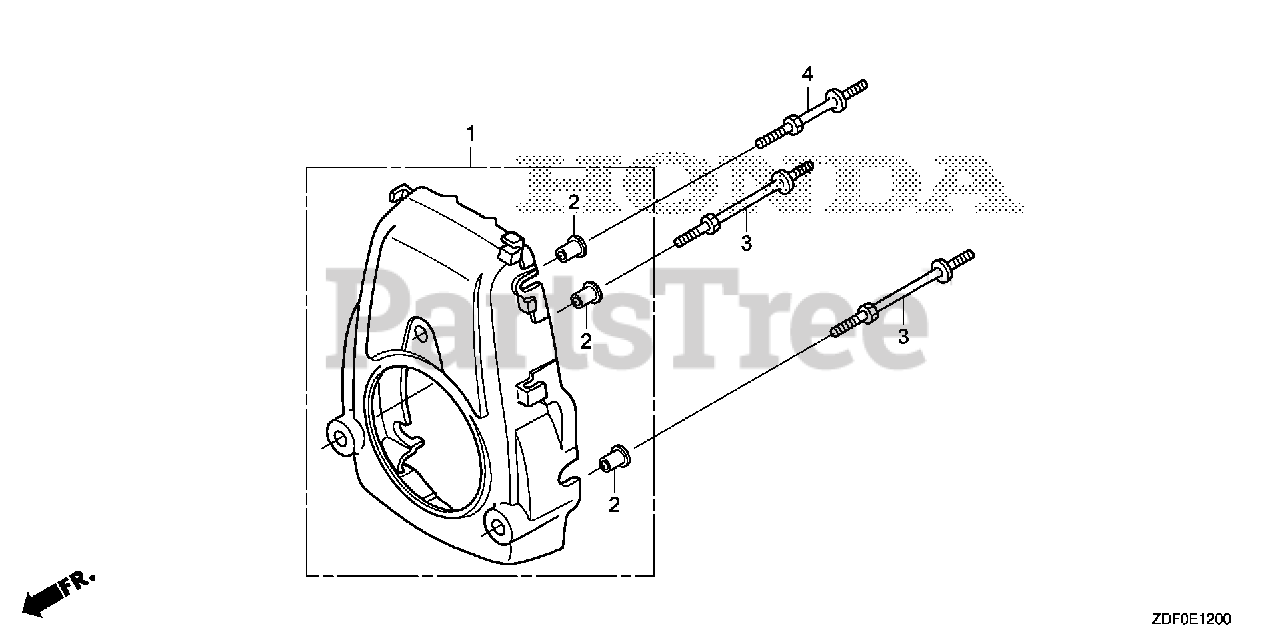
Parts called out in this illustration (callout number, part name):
1	COVER, FAN *R280* (POWER RED)
2	COLLAR, FAN COVER
3	BOLT A, STUD
4	BOLT B, STUD
